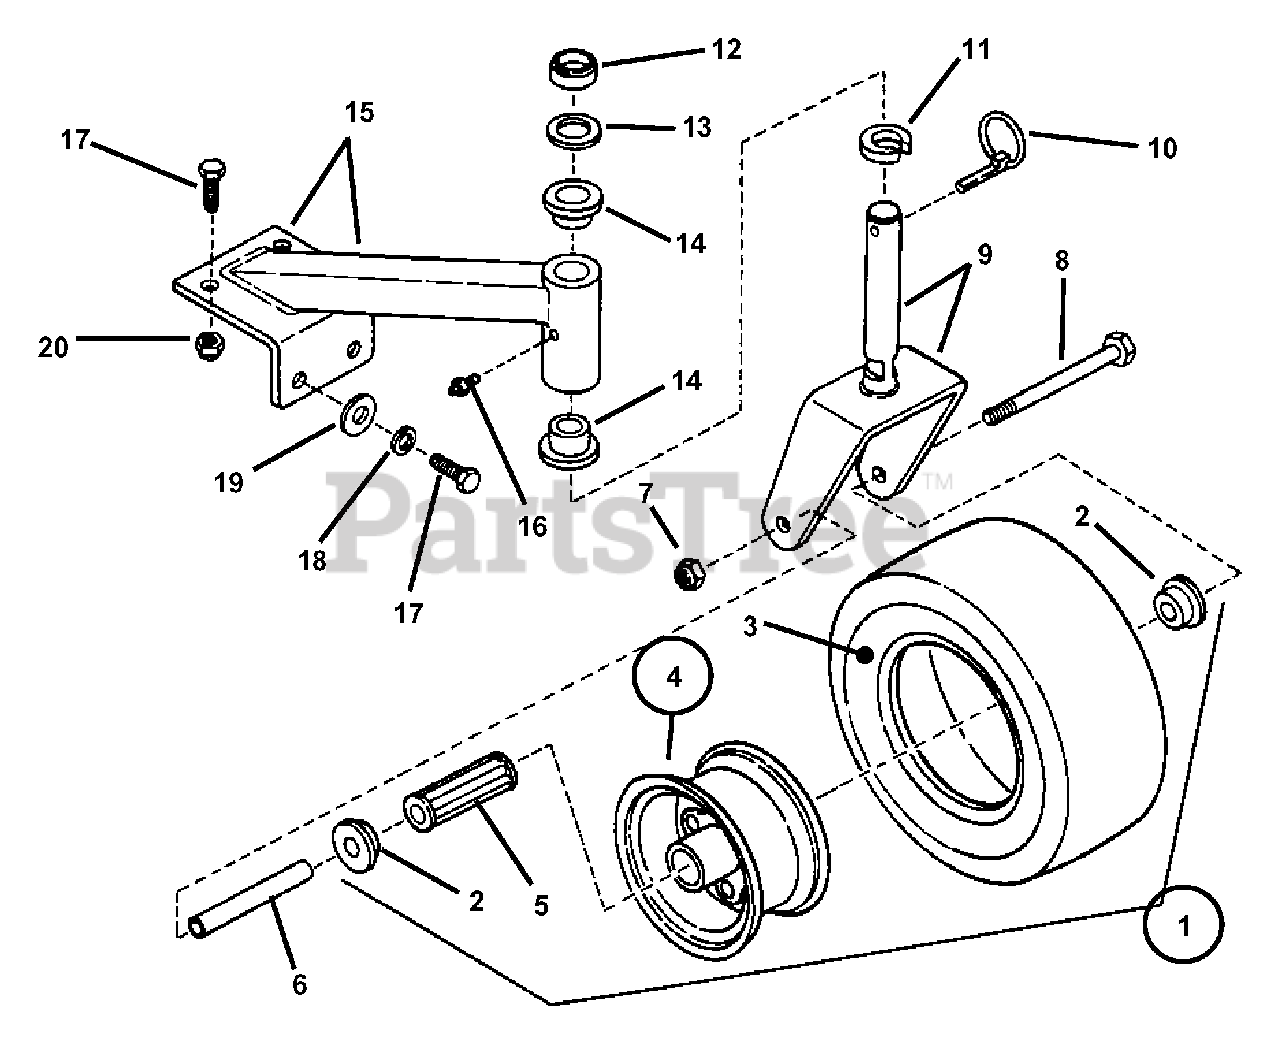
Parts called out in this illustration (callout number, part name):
1	ASSEMBLY, Wheel & Tire
2	RETAINER, Flanged
3	TIRE, 9 x 3.50 - 4
4	ASSEMBLY, Wheel
5	BEARING, Roller
6	SLEEVE, Axle
7	NUT, 1/2-13 Hex (Nyloc)
8	BOLT, 1/2-13 x 5-1/2" Hex Head Cap, Grade 5
9	YOKE, Caster (weldment)
10	PIN, Lynch
11	SPACER
12	SPACER, 1" x 1 3/8 x .30" (PM)
13	BUSHING, 1.025/1.010 I.D. x .048 Thick
14	BUSHING, Caster
15	ASSEMBLY, Caster Support
16	FITTING, Lube
17	SCREW, 3/8-16 x 1" Hex Head Cap, Grade 5
18	WASHER, 3/8 Split Lock
19	WASHER, 3/8" Flat
20	NUT, 3/8-16 Hex (Nyloc)
